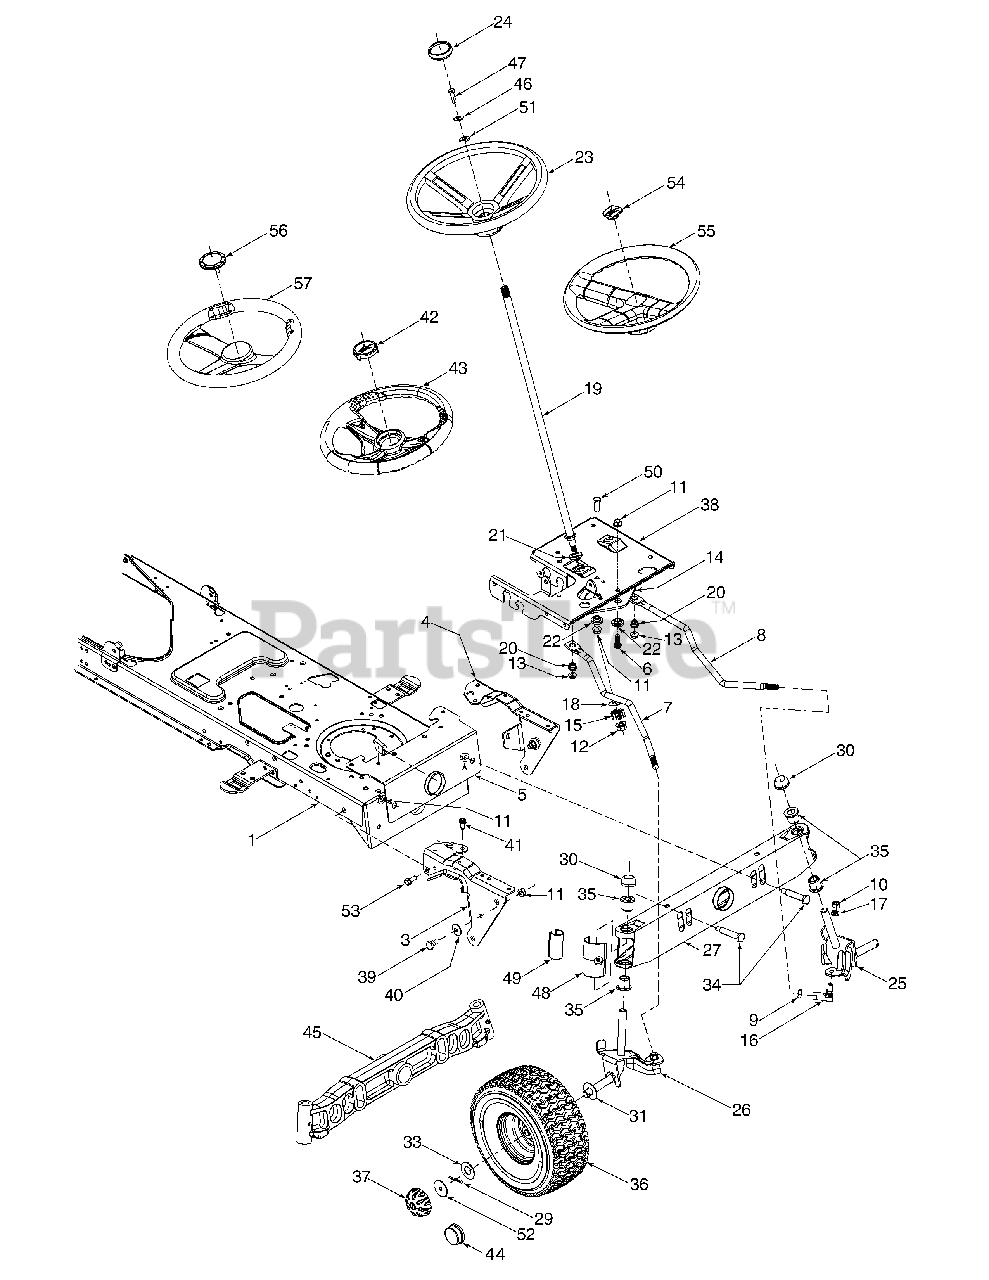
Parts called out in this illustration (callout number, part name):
2	Self-tapping Screw, 16-18 x .625
6	Hex Cap Screw, 3/8-16 x 1.0
7	RH Drag Link
8	LH Drag Link
9	Jam Nut, 7/16-20 (Grade 2)
10	Hex Nut, 3/8-24 (Grade 2)
11	Flange Lock Nut, 3/8-16
12	Flange Lock Nut, 7/16-20
13	Flange Lock Nut, 5/16-18
14	Steering Gear, 11/90 Ratio
15	Steering Pinion Gear
16	Ball Joint, 7/16-20
17	Lock Washer, 3/8
18	Flat Washer, .51 x 1.12 x .06
19	Steering Shaft, .625 OD x 24.4
20	Plastic Bushing, .38 ID
21	Hex Flange Bearing, 5/8
22	Shoulder Spacer, .38 ID
23	Standard Steering Wheel, 13.25
24	Steering Wheel Cap, Round
25	LH Axle Assembly, .625 Diameter
25	LH Axle Assembly, .625/.750 Diameter
26	RH Axle Assembly, .625 Diameter
26	RH Axle Assembly, .625/.750 Diameter
29	Cotter Pin
30	Push Cap, .625
30	Push Cap, .75
33	Flat Washer, .635 x 1.589 x .06
34	Shoulder Screw, .5 x 2.2, 3/8-16
35	Flange Bearing, .632 ID x .937 OD
35	Flange Bearing, .76 ID x .937 OD
36	Wheel Assembly, 15 x 6 x 6
36	Wheel Assembly,15 x 6 x 6
37	Deluxe Hub Cap
39	Shoulder Screw, 3/8-16
40	Bell Washer, .39 x 1.13 x .062
41	Self-tapping Screw, 5/16-18 x .75
42	Cap, Steering Wheel (sprig logo)
43	Steering Wheel, Soft Grip
44	Standard Hub Cap
45	Cast Iron Pivot Bar
46	Bell Washer, .34 x .872
47	Hex Bolt, 5/16-18 x 1.0
48	Pivot Bar End Cap w/ Fitting
49	Pivot Bar End Cap w/o Fitting
50	Hex Screw, 3/8-16 x 1.0
51	Flat Washer, .406 x .875 x .105
52	Flat Washer, .35 x 1.59 x .062
53	Screw, Hex Washer, 5/16-18 x .87
54	Steering Wheel Cap
55	Steering Wheel
56	Steering Wheel Cap
57	Steering Wheel, Soft Grip
